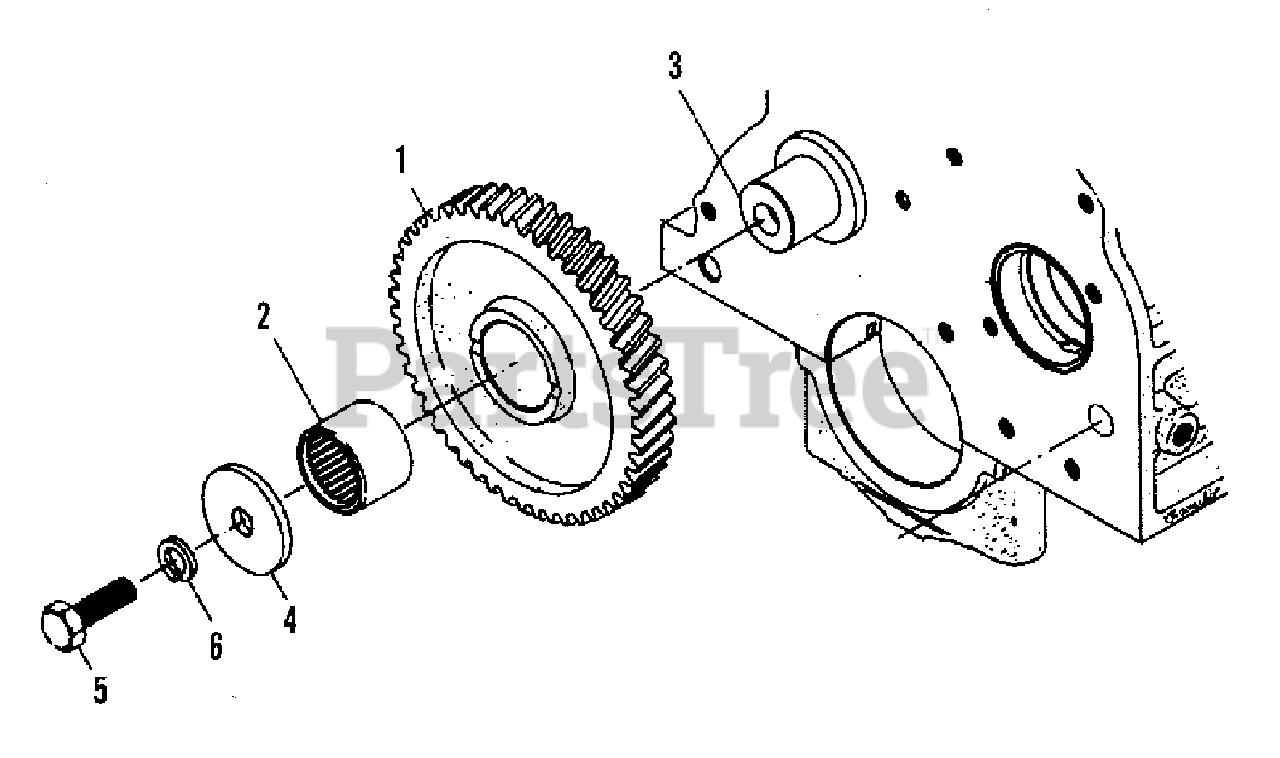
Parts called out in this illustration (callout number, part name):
2	BEARING, needle
3	SHAFT, idler gear (Incl. CYLINDER BLOCK ASSEMBLY)
4	WASHER, thrust
5	BOLT, M10 x 34
6	LOCKWASHER, M10
